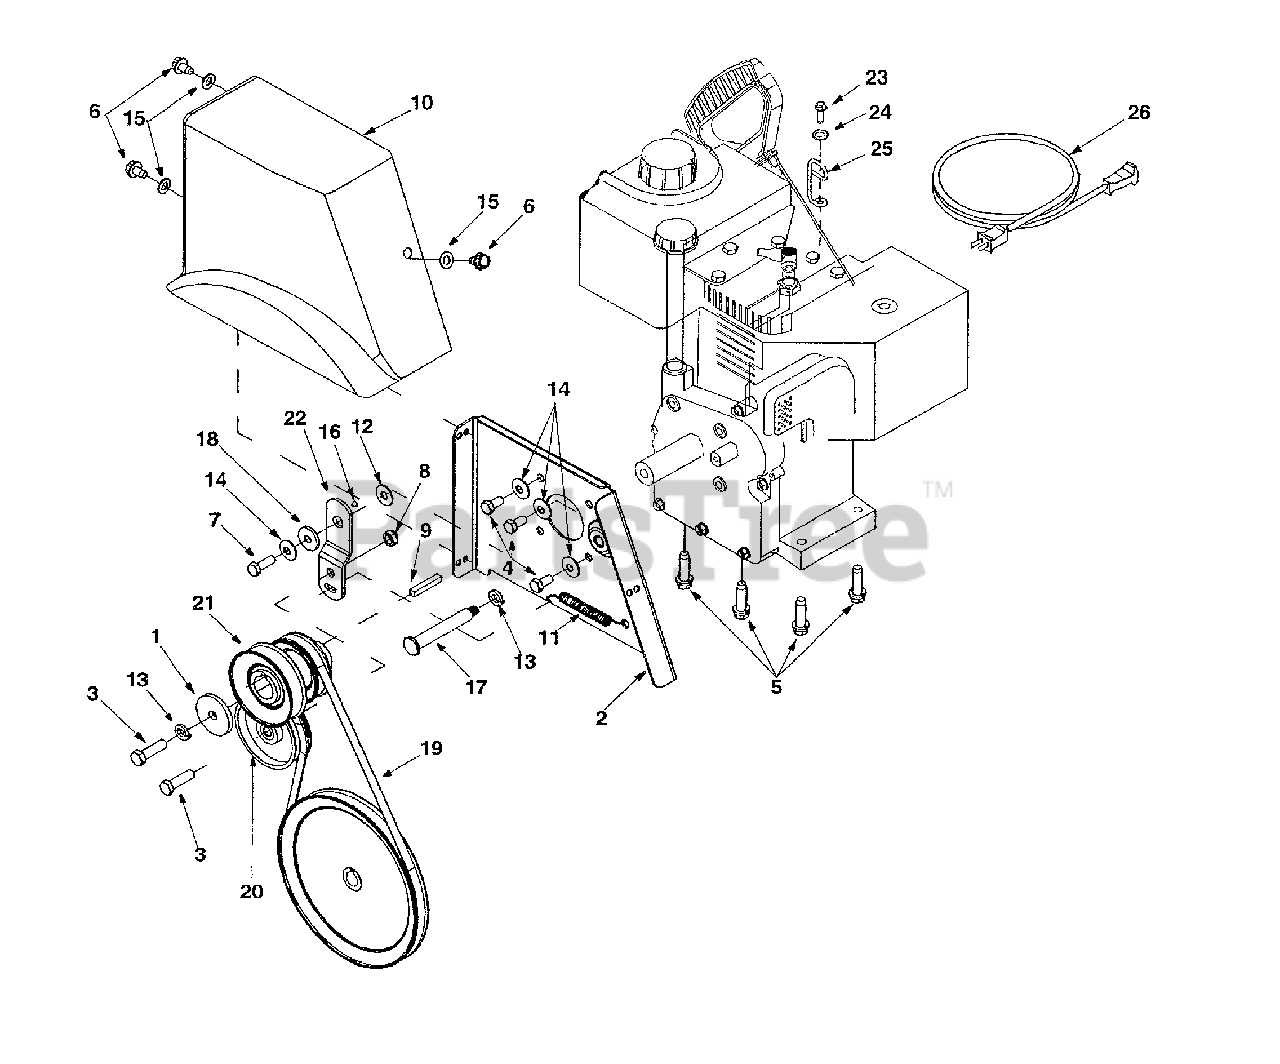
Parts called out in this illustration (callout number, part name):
4	Hex Screw 5/16-24 x .625"
5	TT Sems Screw
6	TT Screw 5/16-18 x 0.5"
7	Hex Lock Screw 5/16-24 x .875"
10	Belt Cover
11	Extension Spring
12	5/16 Washer
13	Lock Washer
14	Beleville Washer
15	Flat Washer
17	Shoulder Screw
18	Shoulder Spacer
19	V-Belt
20	Flat Idler
21	Double Pulley
22	Idler Bracket
23	Hex Lock Nut: 1/4-20
24	Cable Guide
25	Flat Washer
26	Extension Cord: 110V, 3-prong
